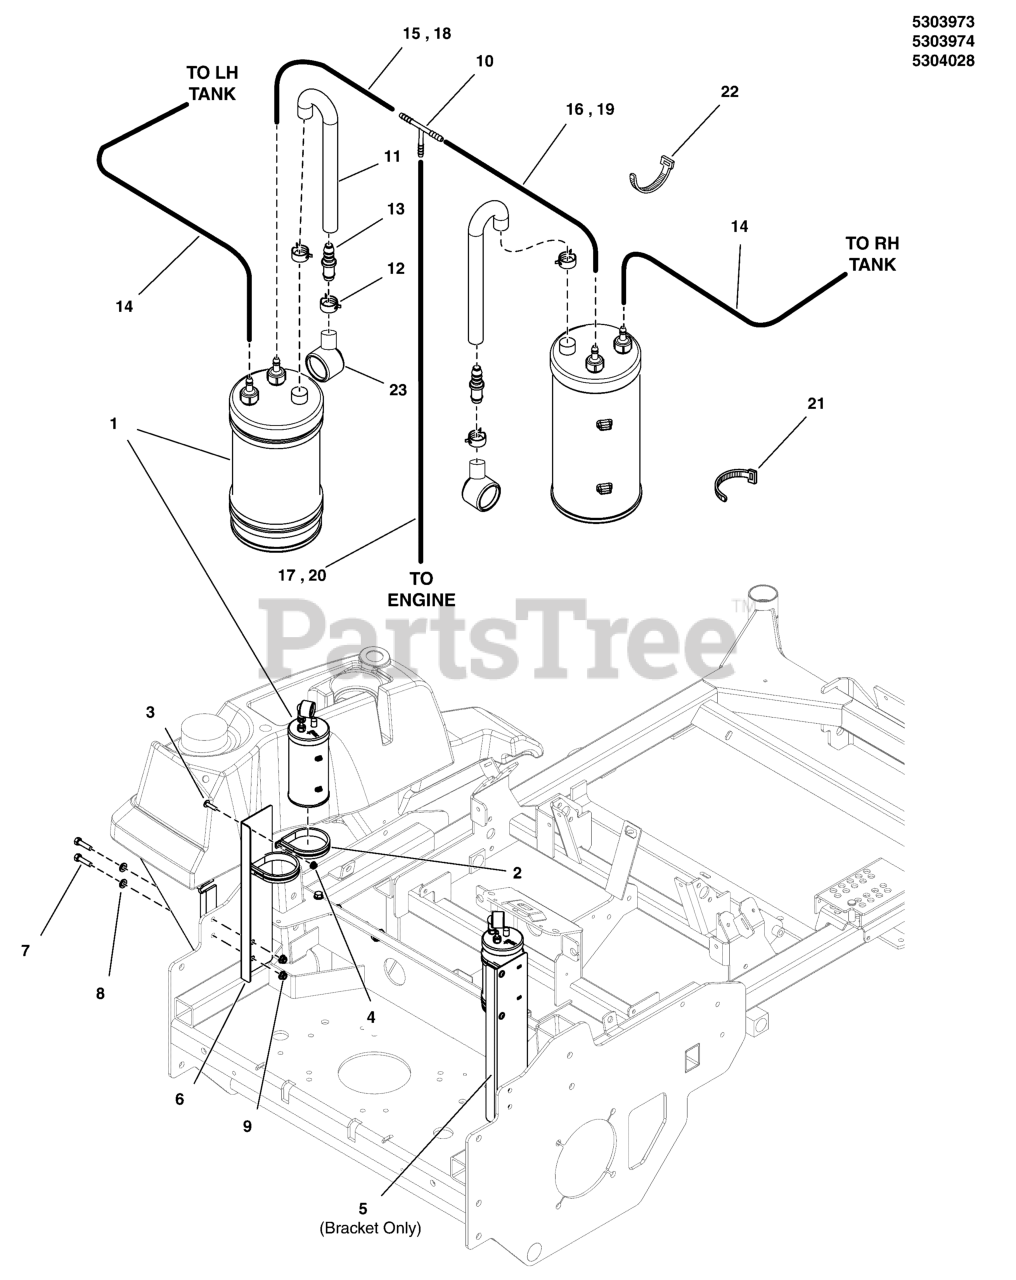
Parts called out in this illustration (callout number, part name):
1	CNSTR, CARB, 6 GAL
2	CLAMP, 3" ID, CUSHIONED, STAINLESS
4	NUT, 1/4-20 HEX NYLOCK FLANGE
5	PLATE, CARB CAN, S200XT, RH - BLK
6	PLATE, CARB CAN, S200XT, LH - BLK
7	BOLT, 5/16-18 X 1-1/4 GD5 CZ
8	WASHER, 5/16 LOCK CZ
9	NUT, 5/16-18 HEX NYLOCK FLANGE
10	FITTING, 3/16" TEE, BARB TYPE, HDPE
11	HOSE, FORMED, EVAP CANISTER
12	CLAMP, HOSE
13	FITTING, STRAIGHT, 10MMX10MM, PLASTIC
14	HOSE, VAPOR, 5MM ID, 10.00 LG
15	HOSE, VAPOR, 5MM ID, 46.00 LG
16	HOSE, VAPOR, 5MM ID, 16.00 LG
17	HOSE, VAPOR, 5MM ID, 10.00 LG
18	HOSE, VAPOR, 5MM ID, 16.00 LG
19	HOSE, VAPOR, 5MM ID, 46.00 LG
20	HOSE, VAPOR, 5MM ID, 25.00 LG
21	TIE, SELF-LOCKING, 15"
22	TIE, SELF-LOCKING, 12"
23	DUST FILTER, CANISTER
